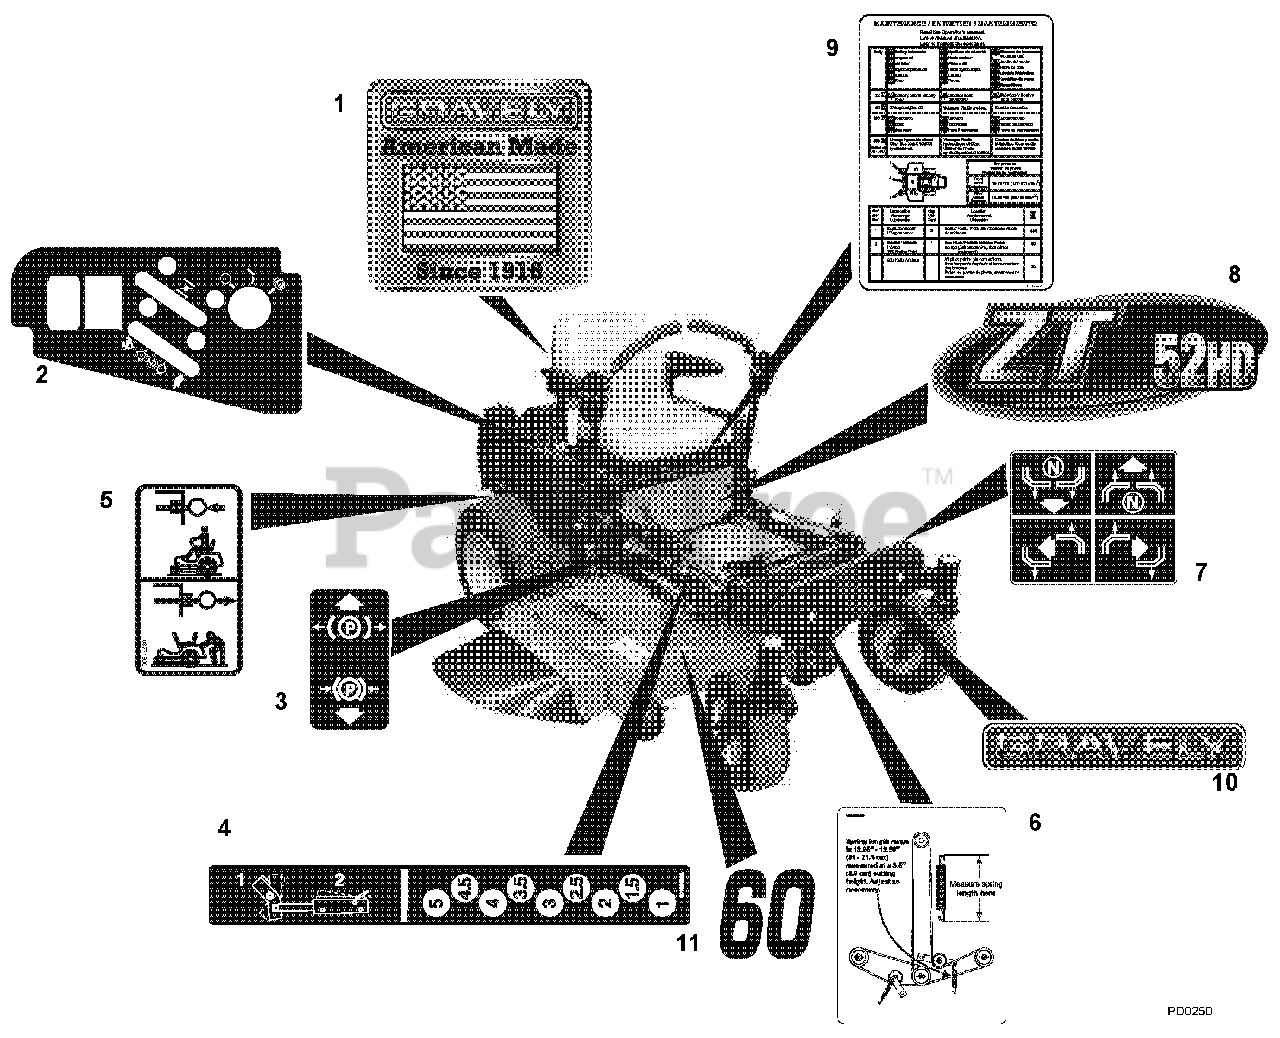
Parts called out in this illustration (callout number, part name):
1	Decal, Gravely American Made
2	Decal, Control Panel
3	Decal, Parking Brake Lever
4	Decal, Height of Cut
5	Decal, Transmission Disconnect
6	Decal, Belt Diagram
7	Decal, Instructional Steering
8	Decal, 48 HD (068)
9	Decal, Maintenance Instructions
10	Decal, 15" Gravely Logo
11	Decal, 60" (070)
